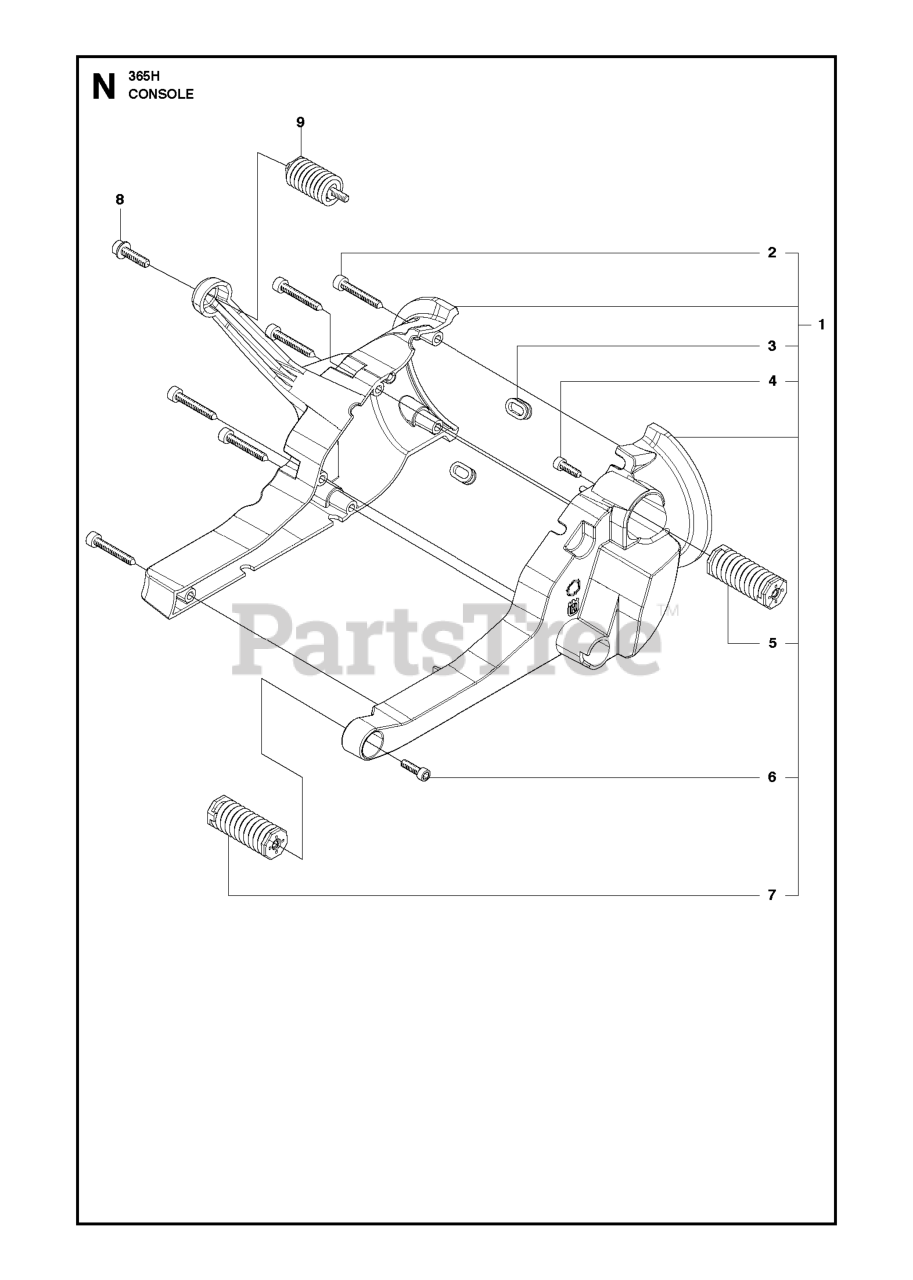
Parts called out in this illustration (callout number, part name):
1	CONSOLE ASSY
5	ANTIVIBRATION ELEMENT
7	ANTIVIBRATION ELEMENT
9	ANTIVIBE MOUNT
